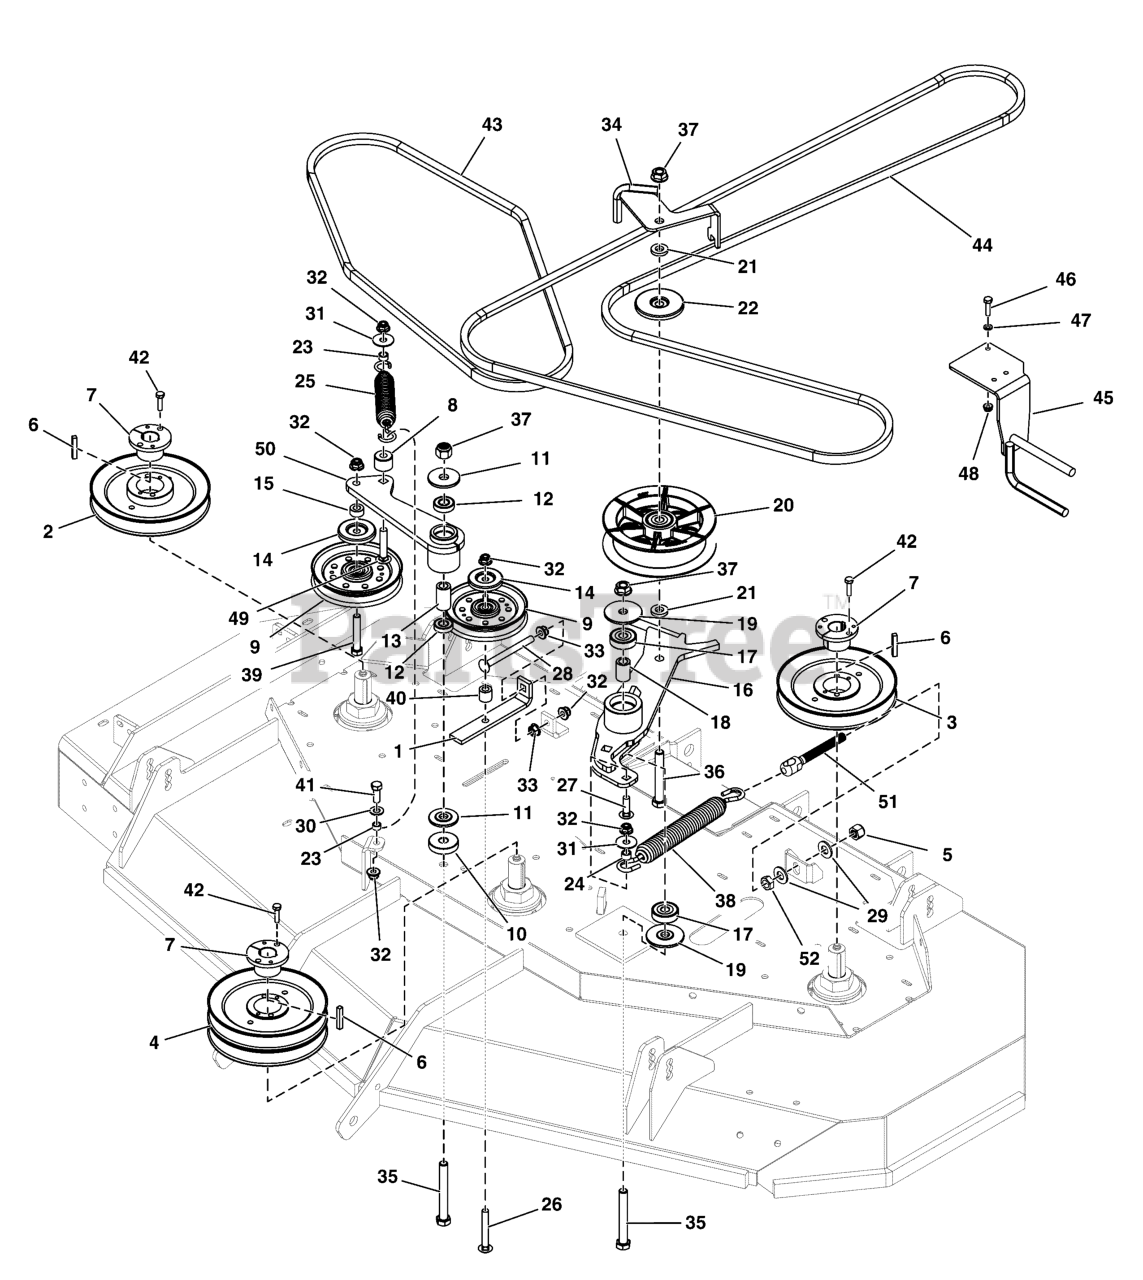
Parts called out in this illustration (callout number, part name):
1	PLATE, IDLER PULLER - BLK
2	PULLEY
3	PULLEY
4	PULLEY
5	NUT, Hex, Nylon Lock, 1/2-20
6	KEY 1/4 SQ X 1 1/2 LONG
7	BUSHING, TAPERED HUB
8	SPACER, .39 X 1.00 X .75, CZ
9	PULLEY, V-IDLER, 5"OD X 3/8", CZ, TE
10	SPACER
11	SPACER, Idler Arm
12	BEARING, Ball
14	SHIELD, PULLEY, 3/8"ID X 2"OD, CZ
15	SPACER, .39 X 1.00 X .38
16	ARM, Idler
17	BEARING, 6203-1/2", SEALED
18	SPACER, .51 X .75 X 1.22, PM, CZ
19	SPACER, IDLER ARM, 1/2 X 2.25
20	PULLEY, IDLER, 5.50, CI, DBL BEARING
21	SPACER, .52 X 1.00 X .22, PM, CZ
22	SHIELD, PULLEY, 1/2"ID X 2-7/8"OD, CZ
23	SPACER, .38 X .50 X .27, CZ
24	SPACER, .39 X .63 X .375, DOM
25	SPRING, Extension (48" Model - SN: 426 & up)(52: Model - SN: 351 & up)
26	BOLT, 3/8-16 X 2-1/2, CARRIAGE, GD5, CZ
27	BOLT, Carriage, 3/8-16 X 1 1/2, GR5
28	BOLT, 3/8-16 X 4-1/2, CARRIAGE, GD5, CZ
29	WASHER, 1/2
30	WASHER, .406
31	WASHER, Fender, 3/8
32	NUT, Hex Flange, Nylock, 3/8-16
33	NUT, Hex, Serrated Flange, 3/8-16 (S/N 616 & up)
34	GUIDE, Belt
35	BOLT, 1/2-13 X 4 GD5 YZ
36	CAPSCREW, Hex Hd, 1/2-13 x 3-1/2
37	NUT, Hex Flange, 1/2-13
38	SPRING, EXT1.22"ODX10.5"FLX.192"WIRE BLK
39	CAPSCREW, Hex Head, 3/8-16 X 1-3/4
41	CAPSCREW, Hex Head, 3/8-16 x 1
42	BOLT, 1/4-20 X 1", GD
43	BELT, B-SEC, 64.00 EL, ARAMID, WRPD
44	BELT, 5V/SPB, 138.50 EL, LG ARAMID, WRPD
45	GUIDE, Belt
46	BOLT, 1/4-20 X 1", GD
47	WASHER, Flat, 1/4
48	NUT, Flange Nylock , 1/4-20
49	BOLT, 3/8-16 X 2, CARRIAGE, GD5, CZ
50	WELD, IDLER ARM, 2 BELT DRIVE - BLK
51	SPRING PULLER, 1/2-20, 6.00
52	NUT, Hex Jam, 1/2-20
